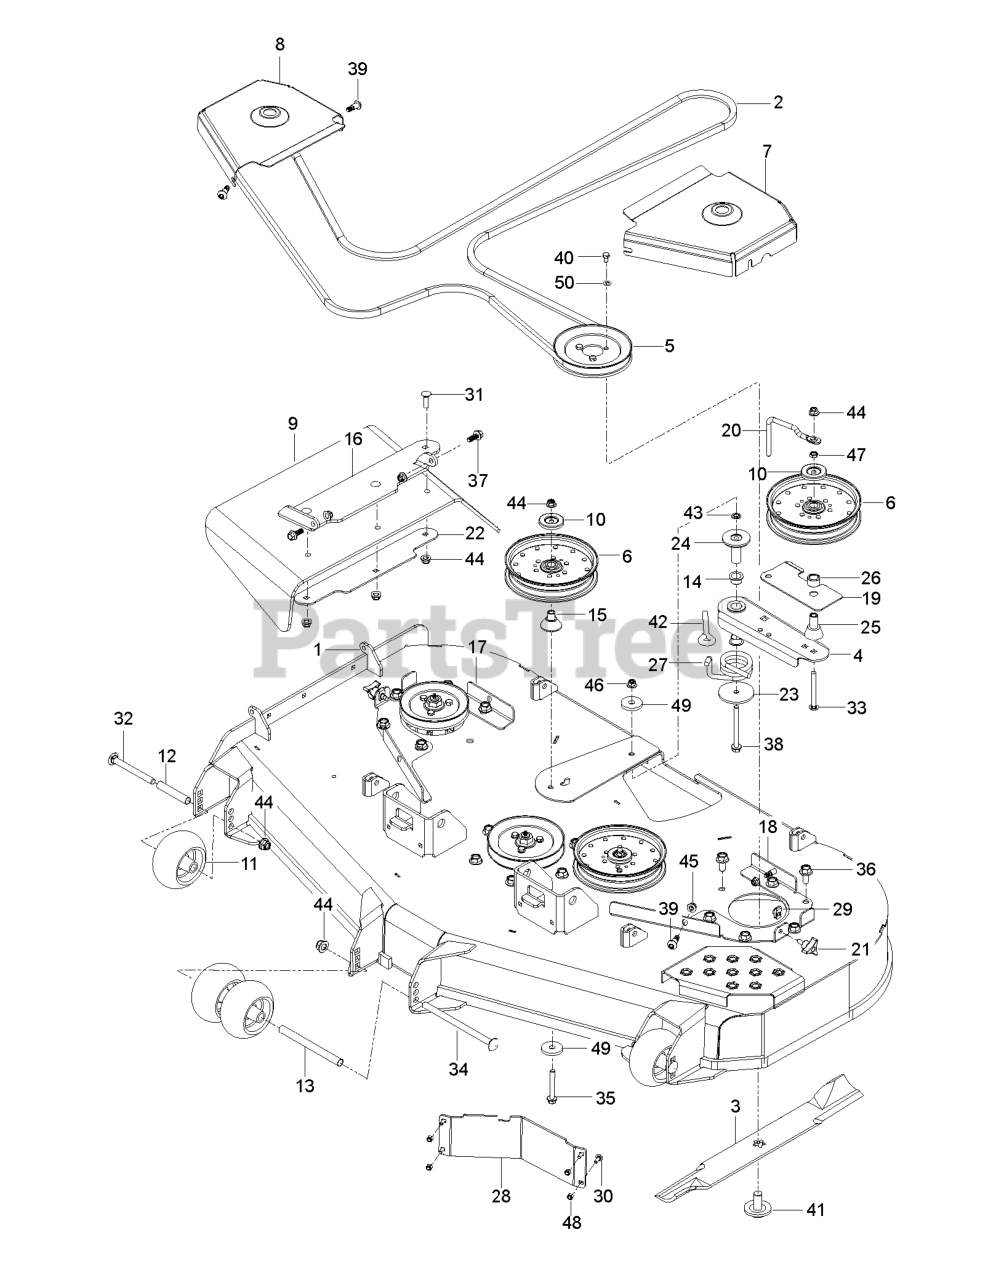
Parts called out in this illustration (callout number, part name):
1	DECK.W/DECALS.60".7GA.ORG
2	BELT 5V 176.00
3	BLADE - HEAVY DUTY 21"
4	ARM.PNT.WLD.TENSIONR.IDLER.BLK
5	PULLEY - 5.93 OVER PINS
6	PULLEY - IDLER 7"
7	COVER.PULLEY.LH.PNT
8	COVER.PULLEY.RH.PNT
9	CHUTE.DISCHARGE
10	DUST SHIELD
11	ROLLER, GAUGE .635 BORN
12	TUBE, ROLLER AXLE
13	TUBE, ROLLER AXLE LONG
14	BEARING, FLANGE
15	BEARING, IDLER ARM
16	BRACKET.CHUTE.ORG
17	BRACKET.PULLEY.COVER.LH.PNT
18	BRACKET.PULLEY.COVER.RH.PNT
19	BELT.GUARD.LOWER.PLATE.PNT.431
20	KEEPER KEEPER., BELT
21	KNOB W/STUD
22	PLATE.BACKING.DISCHARGE.CHT.BK
23	PLATE.SPRING.RETAINER
24	SHAFT.MOUNT.ARM.IDLER
25	SPACER
26	SPACER.PULLEY.INTERMEDIATE
27	SPRING.TORSION.DECK.IDLER.TMSN
28	BAFFLE, DIVERTER 54"/60" LH
29	U-CLIP 5/16-18 NUT RETAINER
30	1/4-20X3/4 CARR BLT
31	BOLT.3/8-14X1.25
32	RHSNB 1/2-13 X 4.75 GR5 ZD
33	BOLT.RDHD SQNK 3/8-16 X 3-1/2
34	RHSNB 1/2-13 X 8 GR5 ZD
35	HHFS 3/8-16 X 2-3/4 GR5 ZD
36	HHFS 1/2-13 X 1 GR5 ZD
37	HHFS 3/8-16 X 1 GRD 5 ZD
38	HHFS 3/8-16 X 4 GR5 ZD
39	SCREW.SHLDR.3/8 X 1/2.5/16-18
40	HCS 5/16-18 X 1/2 GR 5 ZD
41	BLADE BOLT/WASHER
42	EYE BOLT, 3/8 X 4"
43	NUT 3/8 PALNUT RTNG BLK PHOS
44	NUT 3/8-16 HEX FLG NYLOC ZD
45	5/16-18 NYLOC FLANGE NUT
46	NUT, 1/2-13 HEX FLG NYLOC ZD
47	NUT 3/8-16 HEX JAM
48	NUT.1/4-20.HEX.NYLOC.ZD
49	SPINDLE WASHER
50	WASH 5/16 DISC SPRING ZD
